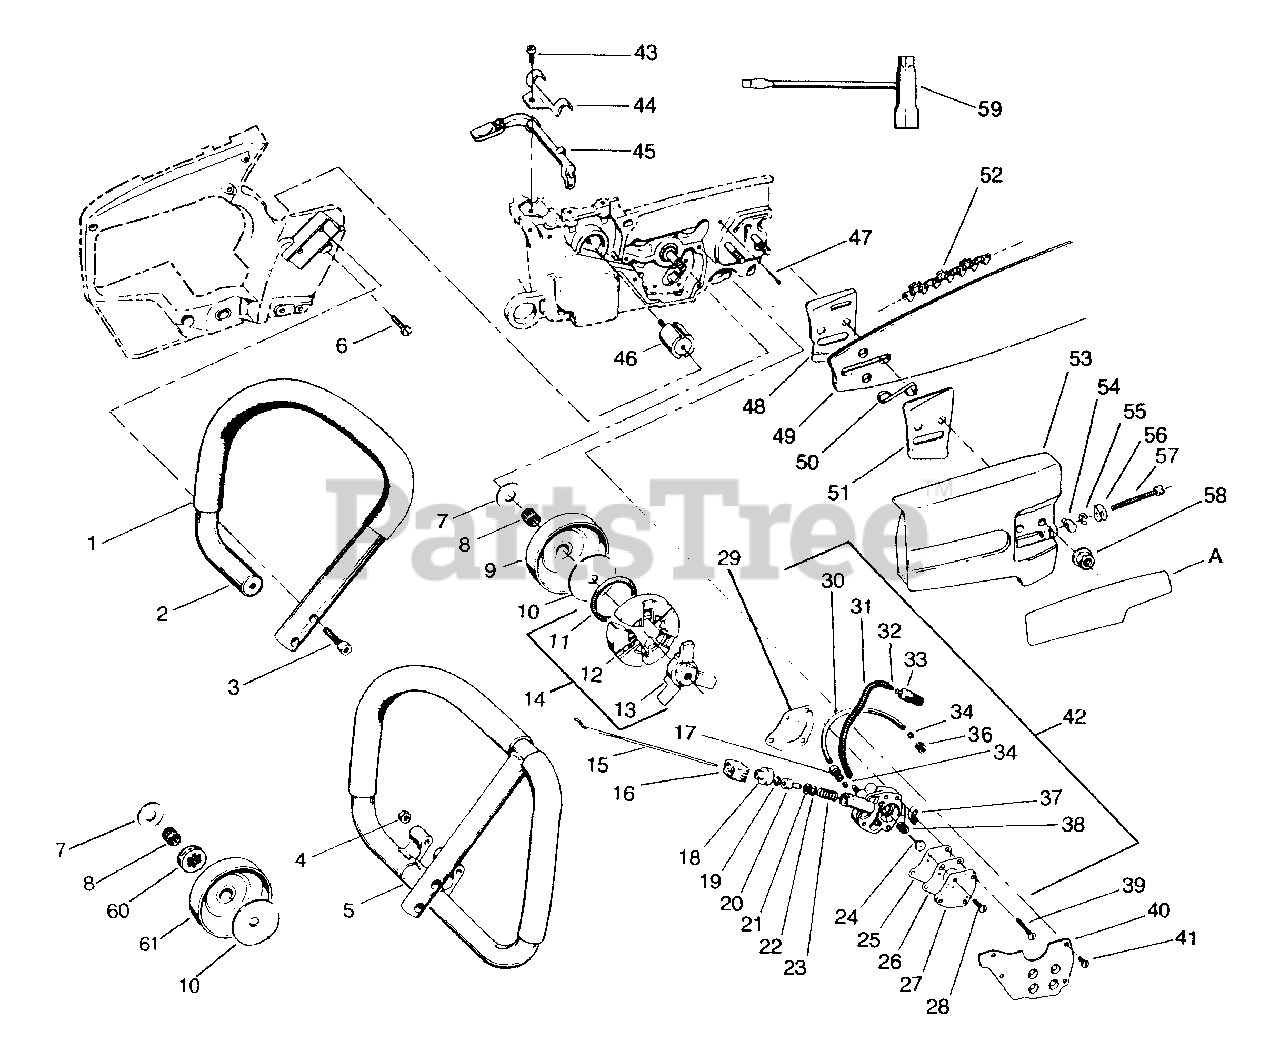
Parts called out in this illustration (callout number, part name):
1	Kit-Handle Grip (Velvet Touch)
2	Handlebar Assembly
3	Screw-1/4-20 1 Socket Hd. Handlebar to Crankcase
4	Locknut-1/4-20-Wraparound Handle
5	Handlebar- Wraparound Handle
6	Screw-10-24 1/2 Pan. Hd. Side Isolator
7	Thrust Washer
8	Bearing-Clutch
9	Drum & Sprocket Assembly
10	Plate Clutch
11	Spring-Clutch
12	Shoe-Clutch
13	Spider-Clutch
14	Clutch Ass'y.
15	Rod- Manual Oiler
16	Boot- Oiler Rod
17	Tubing-Nut
18	Cap -Ott Pump
19	Retainer Ring
20	Plunger
21	Quad Ring
22	Washer-Oiler
23	Spring
24	Pintle
25	Diaphragm
26	Gasket- Cover to Body
27	Cover-Pump
28	Screw-8-16, 5/8 Pan Hd. Oil Pump Cover
29	Gasket- Oiler Ass'y. to Crankcase
30	Discharge Line Oil (Bulk 8115)
31	Spring - Oil Line Protector
32	Oil Line (Bulk 8132)
32	Oil Line Pick-Up Assembly
33	Weight-Oil Pick-up Line
34	Sleeve-1/8 Tubing
36	Tubing Nut-Slotted
37	Foam -Oil Pump Vent
38	Spring-Diaphragm
39	Screw-8-32, 1-Pan. Hd. Pump to Crankcase
40	Cover Plate-Oiler
41	Screw-8-32 5/16 Pan. Hd. Cover Plate
42	Oil Pump Ass'y. Auto/Manual
43	Screw-10-24 3/8 Fil Hd Bracket to Crankcase
44	Bracket Lever to Crankcase
45	Lever - Manual Oiler
46	Isolator Side
47	Kit-Oil Tank Vent Replacement
48	Guide Bar Plate - Inner
49	Guide Bar or Bow Guide
50	"S" Clip -
51	Guide Bar Plate-Outer
52	Chain
53	Bar Clamp Ass'y.
54	Pin- Bar Adj.
55	"E" Ring Adj. Screw
56	"U" Clip Bar Adj.
57	Screw-10-24 2 5/16 Bar Adj.
58	Flange Nut Mounting 5/16-18
59	Scrench
60	Rim Floating
61	Ass'y Drum & Sprocket
A	Decal- Bar Clamp
